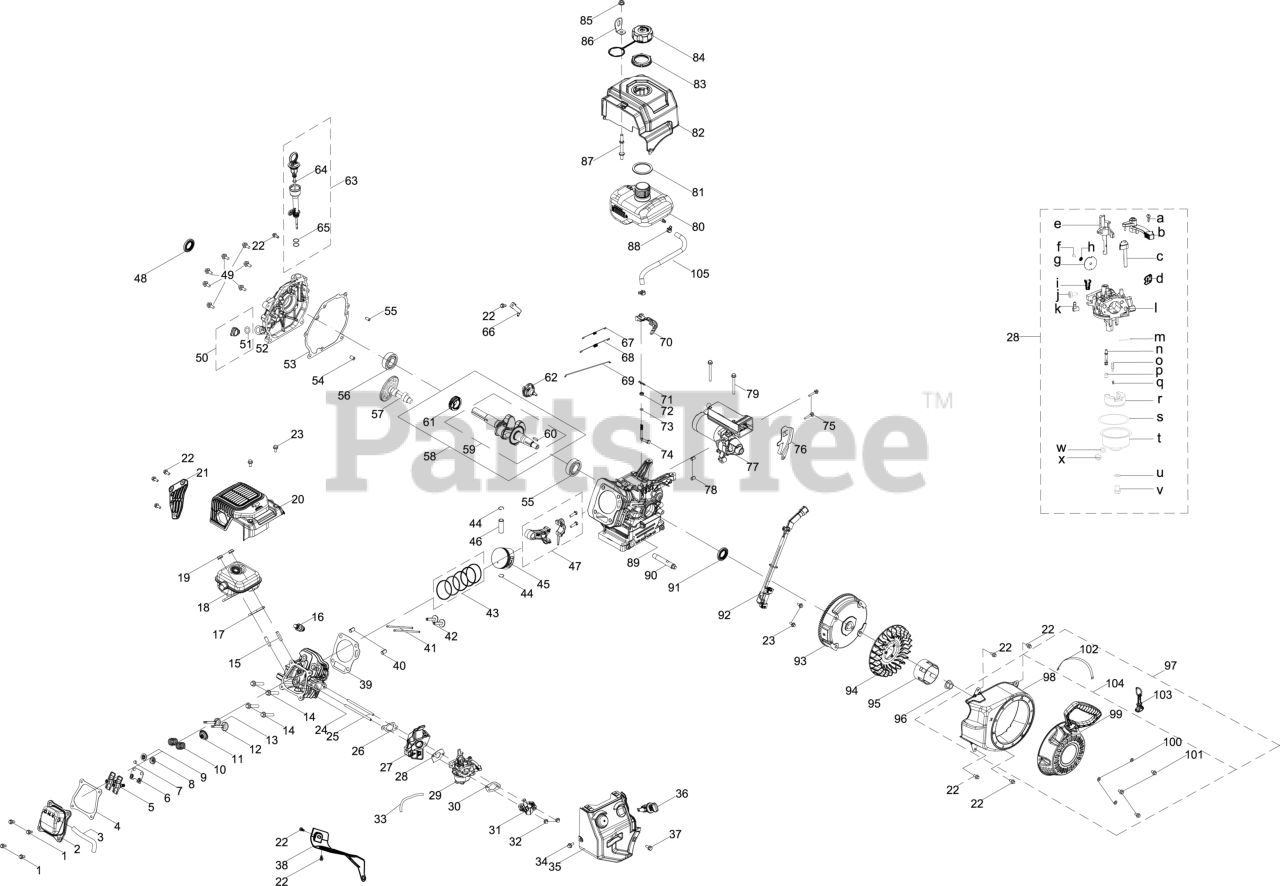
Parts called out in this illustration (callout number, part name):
1	BOLT M6 x 16
2	VALVE COVER
3	BREATHER HOSE
4	VALVE COVER GASKET
5	ROCKER ARM KIT
6	ROCKER ARM BASE
7	VALVE ADJUST NUT
8	EXHAUST VALVE SPRING RETAINER
9	INTAKE VALVE SPRING RETAINER
10	VALVE SPRING
11	INTAKE VALVE SEAL
12	INTAKE VALVE
13	EXHAUST VALVE
14	BOLT M8-1.25 x 55 GR10.9
15	STUD M8 x 36
16	SPARK PLUG (F6RTC/RN11YC/BPR6ES)
17	MUFFLER GASKET
20	MUFFLER GUARD
21	EXHAUST PIPE GUARD
22	BOLT M6-1 x 12 GR8.8
23	BOLT M6-1 x 25 GR8.8
24	CYLINDER HEAD
25	STUD M6 x 90
26	CARBURETOR INSULATOR GASKET
27	CARBURETOR INSULATOR
28	CARBURETOR GASKET
29	CARBURETOR
30	CARBURETOR GASKET PLATE
31	AIR INTAKE
33	FUEL HOSE 3.2x6.5x115
34	BOLT M6-1 x 14 GR8.8
35	CONTROL PANEL
36	ENGINE KEY SWITCH ASSEMBLY
37	BOLT M6-1 x 18 GR8.8
38	AIR SHIELD
39	CYLINDER HEAD GASKET
40	PIN (10MMx16MM)
43	PISTON RING 4PC SET
44	PISTON PIN SNAP RING
47	CONNECTING ROD
49	BOLT M8-1.25 x 32 GR5.8
51	O-RING 15.8 x 2.5
52	CRANKCASE COVER
53	CRANKCASE GASKET
54	DOWEL PIN 9 X 14
55	DOWEL PIN 7 X 14
58	CRANKSHAFT (W/TIMING GEAR)
59	CRANKSHAFT
60	WOODRUFF KEY
61	DRIVE TIMING GEAR
62	GOVERNOR GEAR ASSEMBLY
64	DIPSTICK O-RING
65	OIL FILL TUBE O-RING
66	GOVERNOR SPRING BRACKET
67	GOVERNOR SPRING
68	THROTTLE SPRING
69	THROTTLE LINKAGE
70	GOVERNOR LEVER
74	GOVERNOR SHAFT
75	BOLT M6-1 x 32 GR8.8
76	LOWER HOUSING
77	ELECTRIC STARTER
78	DOWEL PIN
79	HEX CAP SCREW M6x65
82	FUEL TANK SHROUD
83	FUEL TANK NUT
85	NUT M8
87	STUD M8 1.0x90
88	HOSE CLAMP
90	OIL DRAIN PIPE
92	IGNITION MODULE
94	COOLING FAN
95	STARTER CUP
96	FLYWHEEL NUT
97	Recoil Starter
98	BLOWER HOUSING
99	RECOIL STARTER ASSEMBLY
100	RECOIL FLAT WASHER
101	BOLT M6 x 10
102	CABLE TIE - 3 x 150
103	IGNITION KEY
104	RECOIL STARTER
105	FUEL HOSE 6.3x12.5x270
